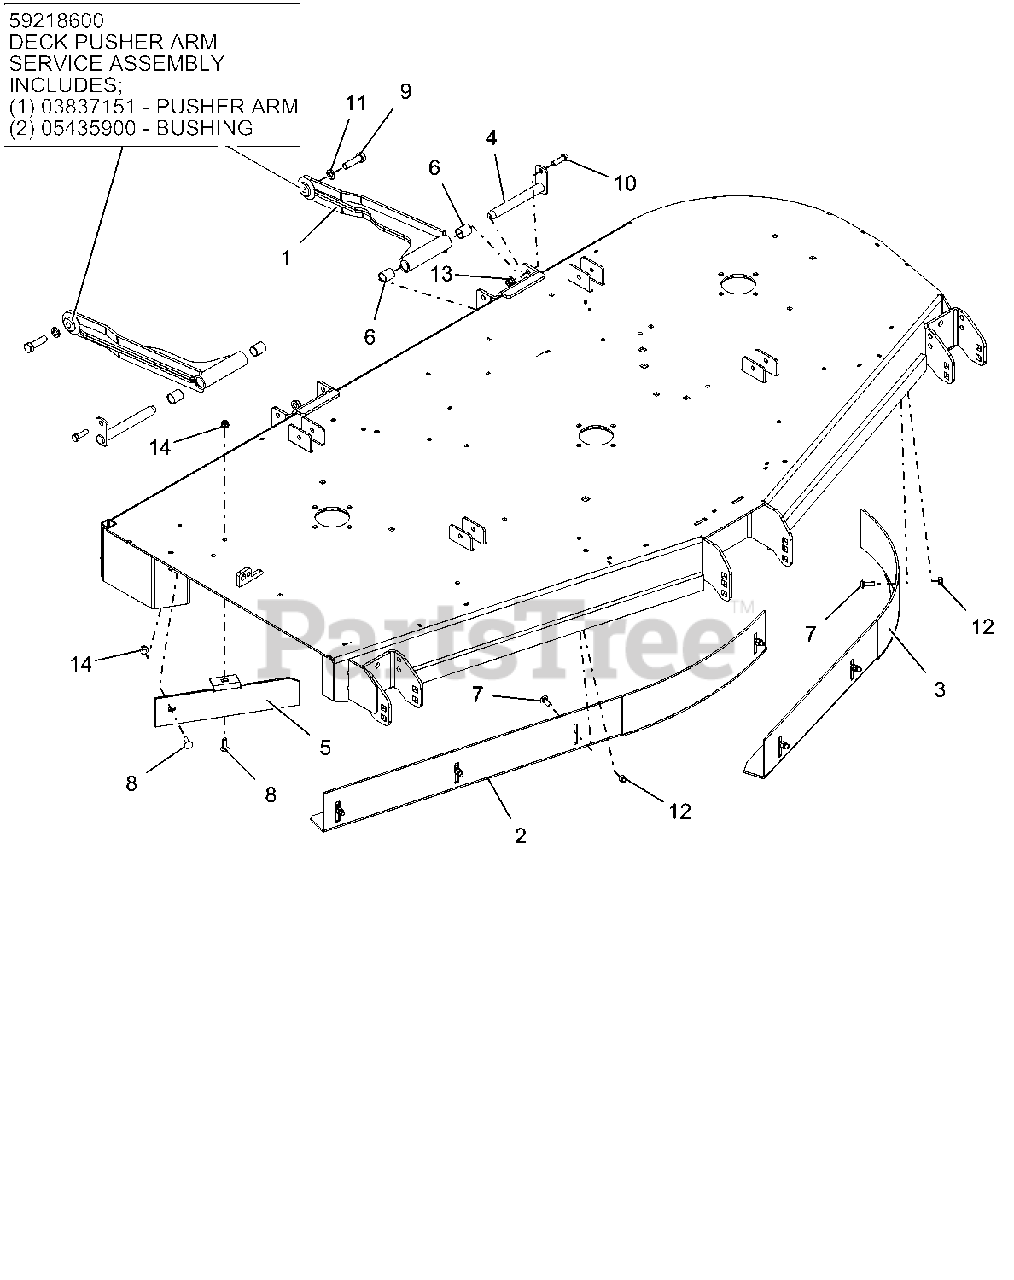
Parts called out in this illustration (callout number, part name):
1	BRG, .750 X .875 X 1.000
1	DECK STABILIZER ARM W/BUSHINGS
1	DECK STABILIZER ARM - BLACK
2	72" RH VACUUM BAFFLE WLDMT-BLK
3	72" LH VACCUM BAFFLE WLDMT-BLK
4	WELDMENT, MOWER MTG. PIN
5	72" DISCHARGE BAFFLE - RED
6	BRG, .750 X .875 X 1.000
7	BLT-RDHDSQNK .31-18X1.00 G5YZ
8	BLT-RDHDSQNK .31-18X1.00 G5YZ
9	BLT-HEX .50-13X1.75 GR5EP80 YZ
10	BLT-HEX .38-16X1.25 GR5 YWZC
11	WSHR-LK .50X.125 REG YWZC
12	NUT-LK-NYL .312-18 YWZC
13	NUT-LK-NYL-FLG .38-16 YWZC
14	NUT-LK-NYL-FLG .31-18 YWZC
